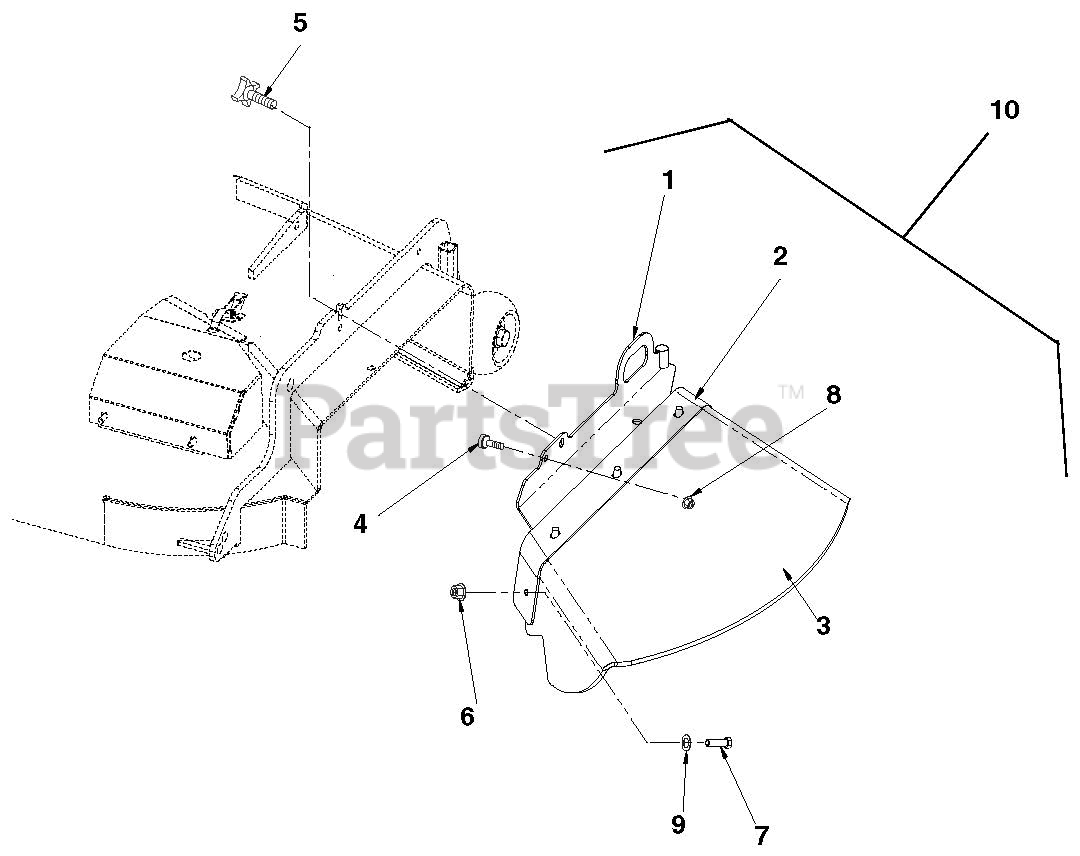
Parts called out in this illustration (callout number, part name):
1	WLDT, DISCH CHUTE MNT
2	PLATE, DISCHG SHIELD SUPPORT
3	SHIELD, RUBBER DISCHARGE
4	BUMPER, RUBBER
5	KNOB, 3/8 X 1.25 - 4 PRONG
6	LOCKNUT, 3/8-16 WHIZ Y
7	BOLT, 3/8-16X1.00 CRG 5 Y
8	LOCKNUT, 5/16-18 WHIZ Y
9	WASHER, .500 REG FLAT Y
10	ASSY, DISCHARGE - RUBBER
